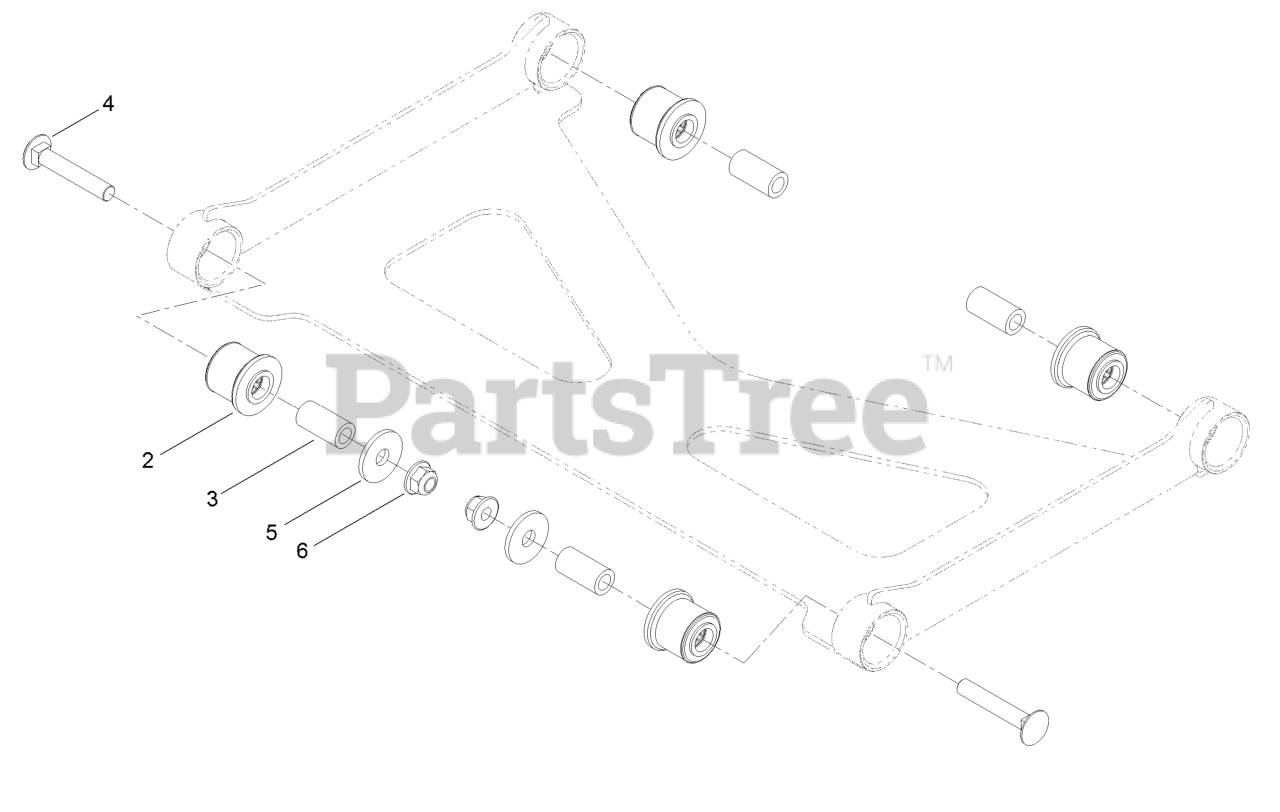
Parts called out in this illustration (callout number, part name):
2	Bushing-Rubber, Suspension
4	Screw-CARR
5	Washer
6	Nut-HF, NI
